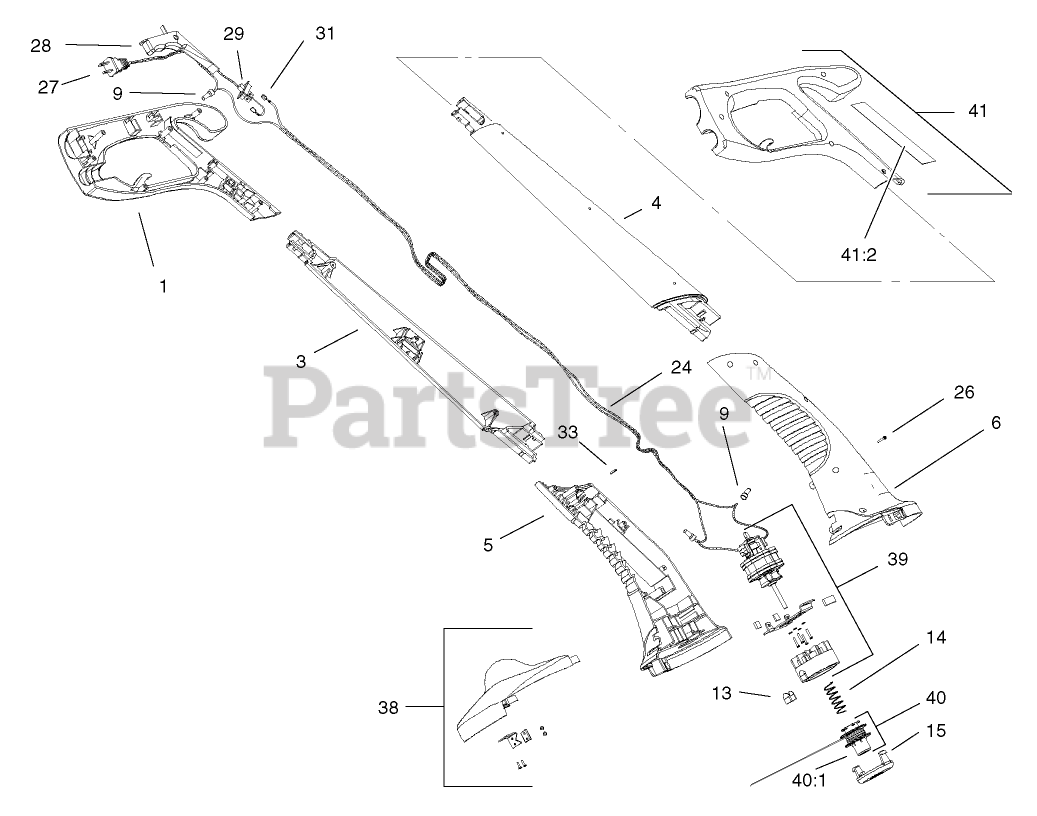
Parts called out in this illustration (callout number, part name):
1	HANDLE-LH
3	MID-SECTION, LH
4	MID-SECTION, RH
5	HOUSING-MOTOR, LH
6	HOUSING-MOTOR, RH
9	CONNECTOR-WIRE
13	EYELET
14	SPRING-COMPRESSION
15	CAP-SMALL
27	PLUG-INPUT
28	TRIGGER-ON/OFF
31	TERMINAL-FEMALE
33	PIN-RETAINING
38	SHIELD ASM
39	MOTOR/DRUM ASM
40	SPOOL ASM
40:1	SPOOL
41:2	DECAL-SERIAL/WARNING
